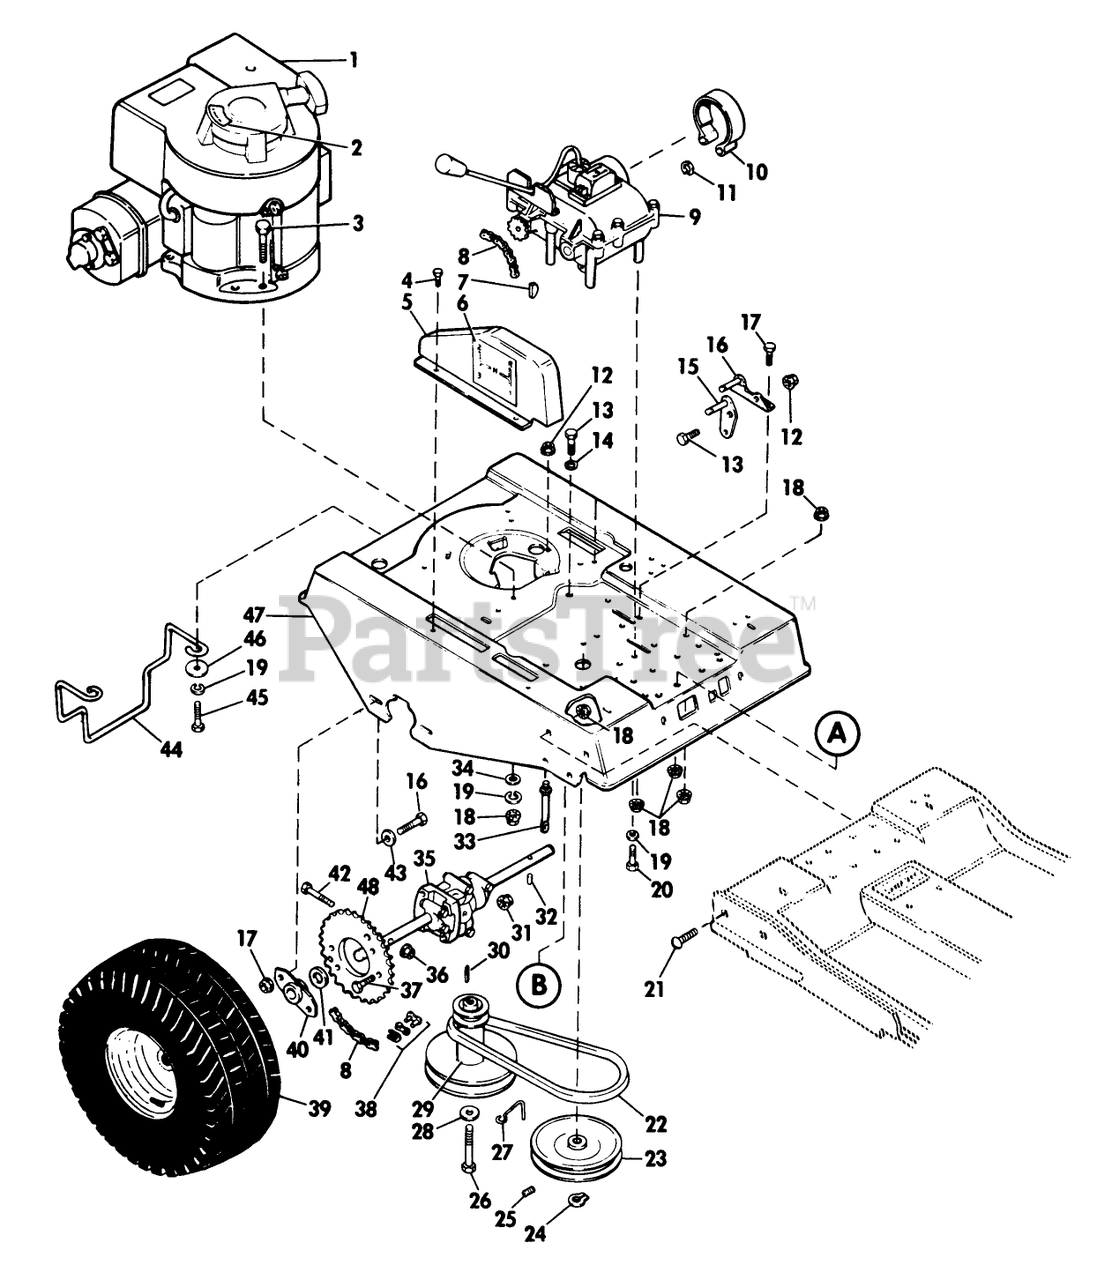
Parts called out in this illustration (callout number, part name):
1	Engine Model 5 H.P. Manual Start
2	Decal Start Instructions
3	Screw-Engine Mounting
5	Chain Guard
6	Decal Shift Pattern
8	Chain-Drive
9	Transmission
10	Brake Band Assembly
11	Ring-Grip
13	Screw
14	Washer
15	Pivot Assembly
16	Bracket Assembly
18	NUT
21	Bolt
22	V-Belt
23	Pulley Assembly
26	Screw
28	Washer
29	Engine Sheave Assembly
30	Key
31	Nut
32	Roll Pin
33	Eyebolt
35	Differential Assembly
36	LOCKNUT
37	Screw
38	Link-Chain Drive
39	Wheel and Tire Assembly-Rear
40	Bracket Assembly-Rear Axle
41	Washer
44	Retainer-Blade Belt
45	Screw
47	Frame-Engine Mounting
48	Sprocket
